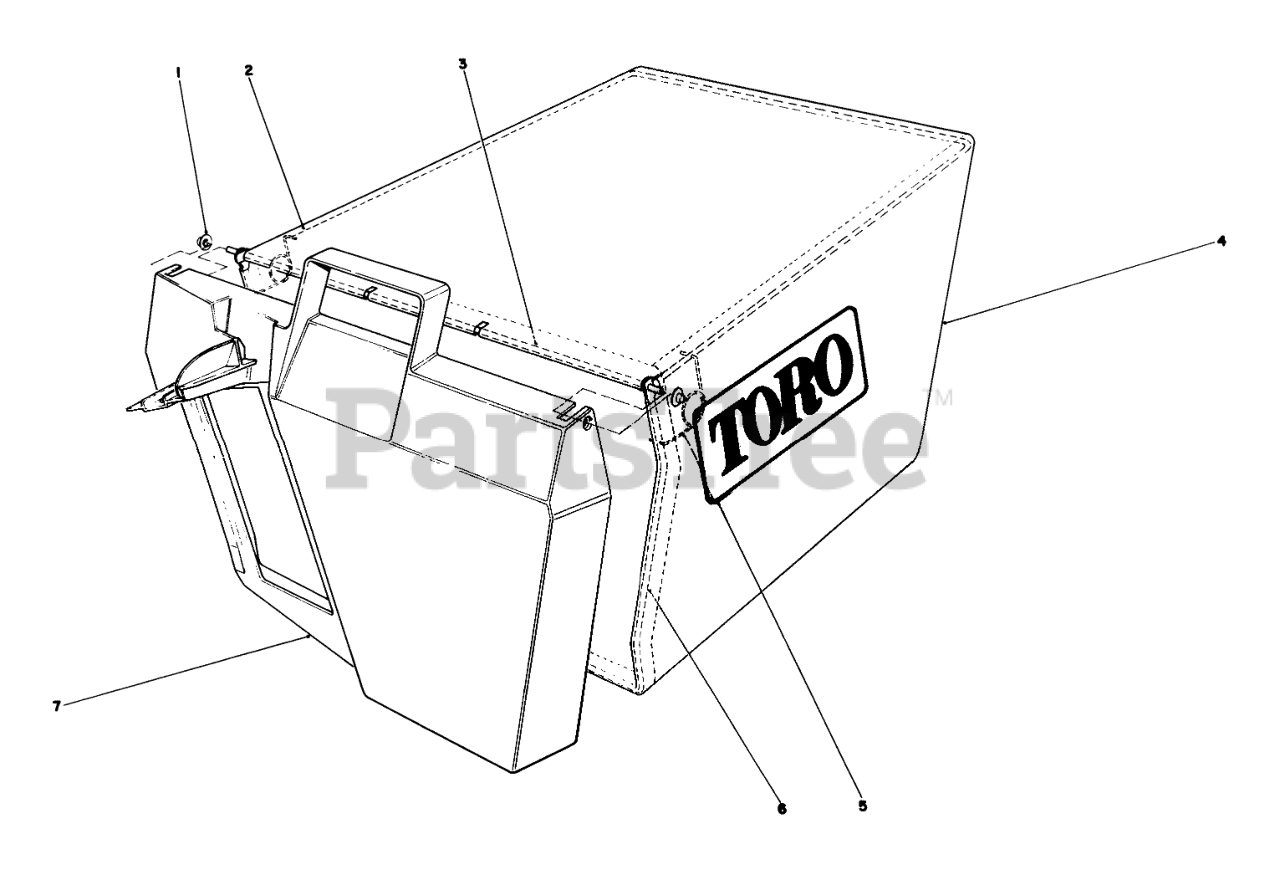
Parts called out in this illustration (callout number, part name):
1	NUT-PUSH
2	FRAME-BAG, UPPER
3	Hinge Bag Door
4	Bag
5	SPRING
6	BAG FRAME
7	BAG DOOR
